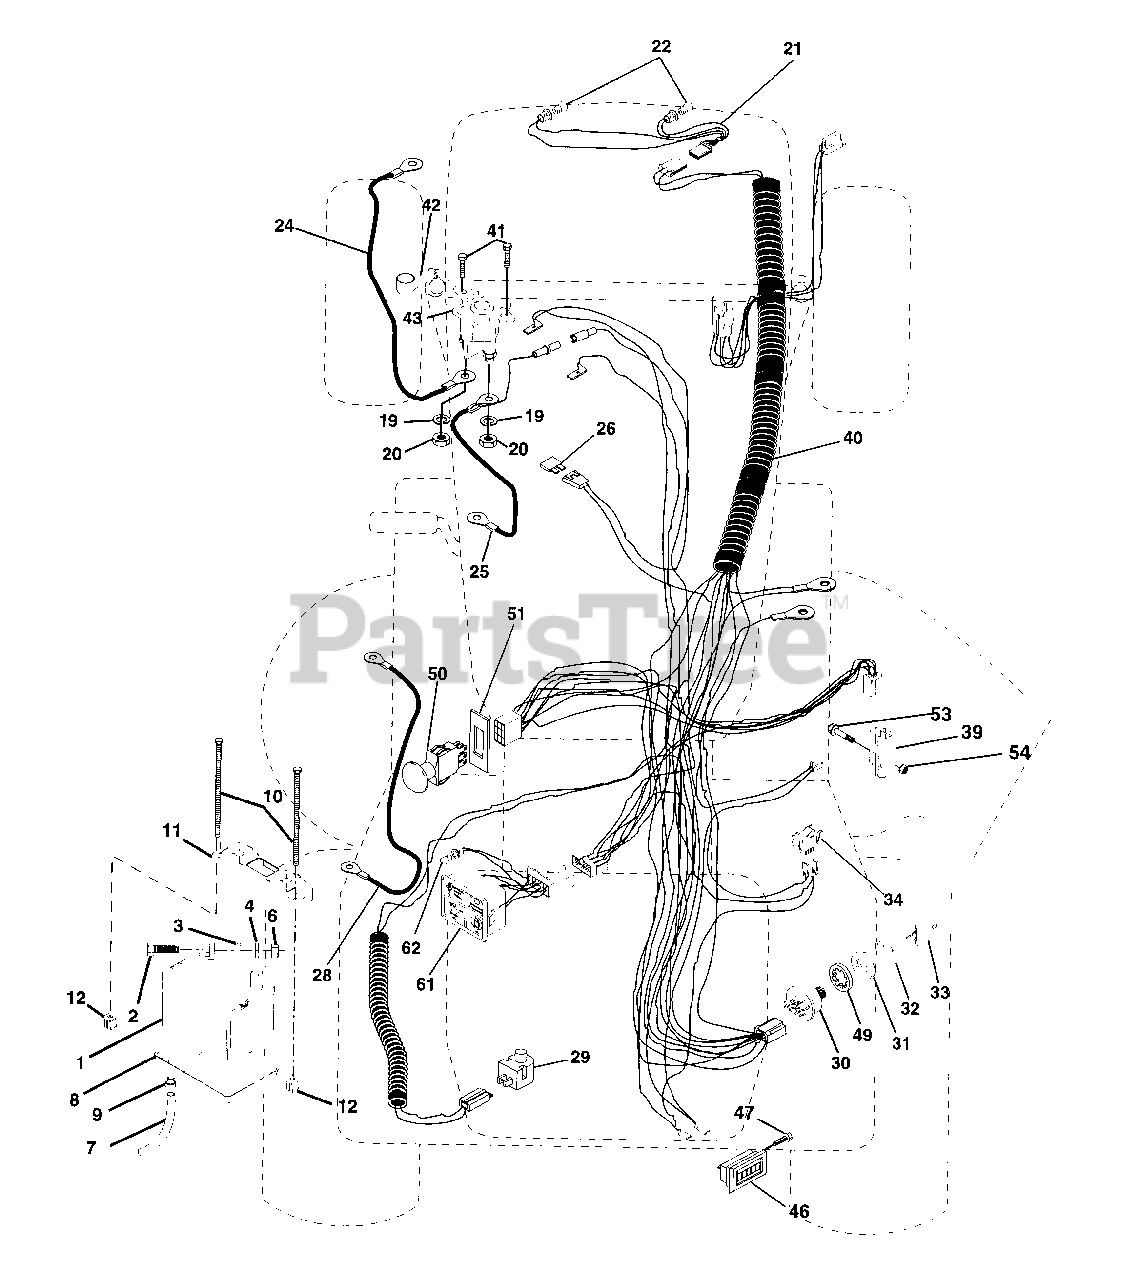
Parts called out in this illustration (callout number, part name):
1	Battery
2	Bolt Hex Head 1/4-20 x 3/4
3	Washer, Lock 1/4
4	Washer 9/32 x 5/8 x 16 Ga
6	Nut Fin Hex 1/4-20
7	Tube Plastic
8	Tray, Battery
9	Clamp, Hose
10	Bolt, Btr Frt 1/4-20 x 7-1/2 Zinc
11	Holddown Battery Dash Mount
12	Nut Push Nylon 1/4" Battery Frt.
19	Washer, Lock 1/4
20	Nut, Jam Hex 1/4-20
21	Harness Socket Light w/4152J
22	Bulb Light
24	Cable, Starter
25	Cable, Battery
28	Cable, Ground
29	Switch, Plunger
30	Switch, Ign
31	Nut, ignition Switch
32	Cover Switch Key
34	Switch, Light
39	Intlk Switch
40	Harness Ign.
41	Screw 1/4-20 x 1/2
42	Cover, Terminal Red
43	Solenoid
46	Meter Hour
47	Screw #10-24 x 1/2
49	Washer, Lock internal Tooth 5/8
50	Switch, PTO
51	Ring Retainer PTO
53	Screw Hex Washer Hd #10-32 x 1
54	Nut Keps #10-32
61	Light Pkg Asm
62	Bulb, Light Pkg.
